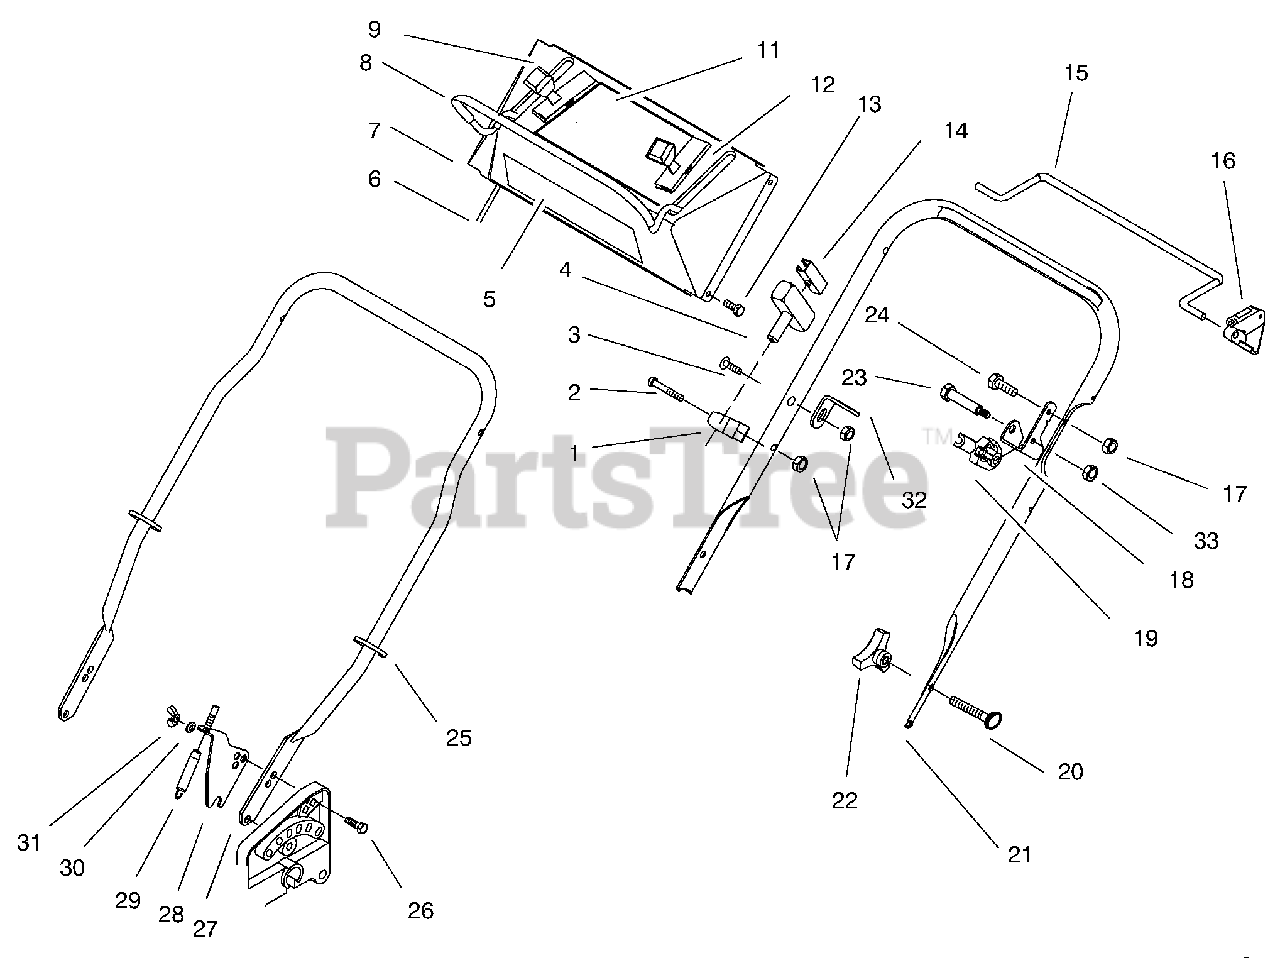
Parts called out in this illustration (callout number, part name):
1	Guide-Rope
4	Handle-Rope
5	Decal-Control Panel
6	Cable-Brake
7	Panel-Control (Model No. 10422) Incl. Ref. #11)
8	Bail-Brake
9	Control Ground Speed (Model No. 10518 & 10523)
11	Decal-Control Panel (Model No. 10422)
12	Control-Throttle
14	Insert-Handle
15	Bail-Control (Model No. 10518 & 10523)
16	Stop-Pivot (Model No. 10518 & 10523)
18	Bracket-Cam
19	Brake-BBC Cam
20	Screw-Handle
21	Handle-Upper
22	Knob-Handle
23	Bolt-Shoulder
24	Screw-Hex. Hd.
25	Tie-Cable
26	Bolt-Carriage
27	Handle-Lower
28	Bracket-Traction Cable (Model No. 10518 & 10523)
29	Cable-Traction (Model No. 10518 & 10523)
32	Bracket-Cable
33	Nut-Lock
